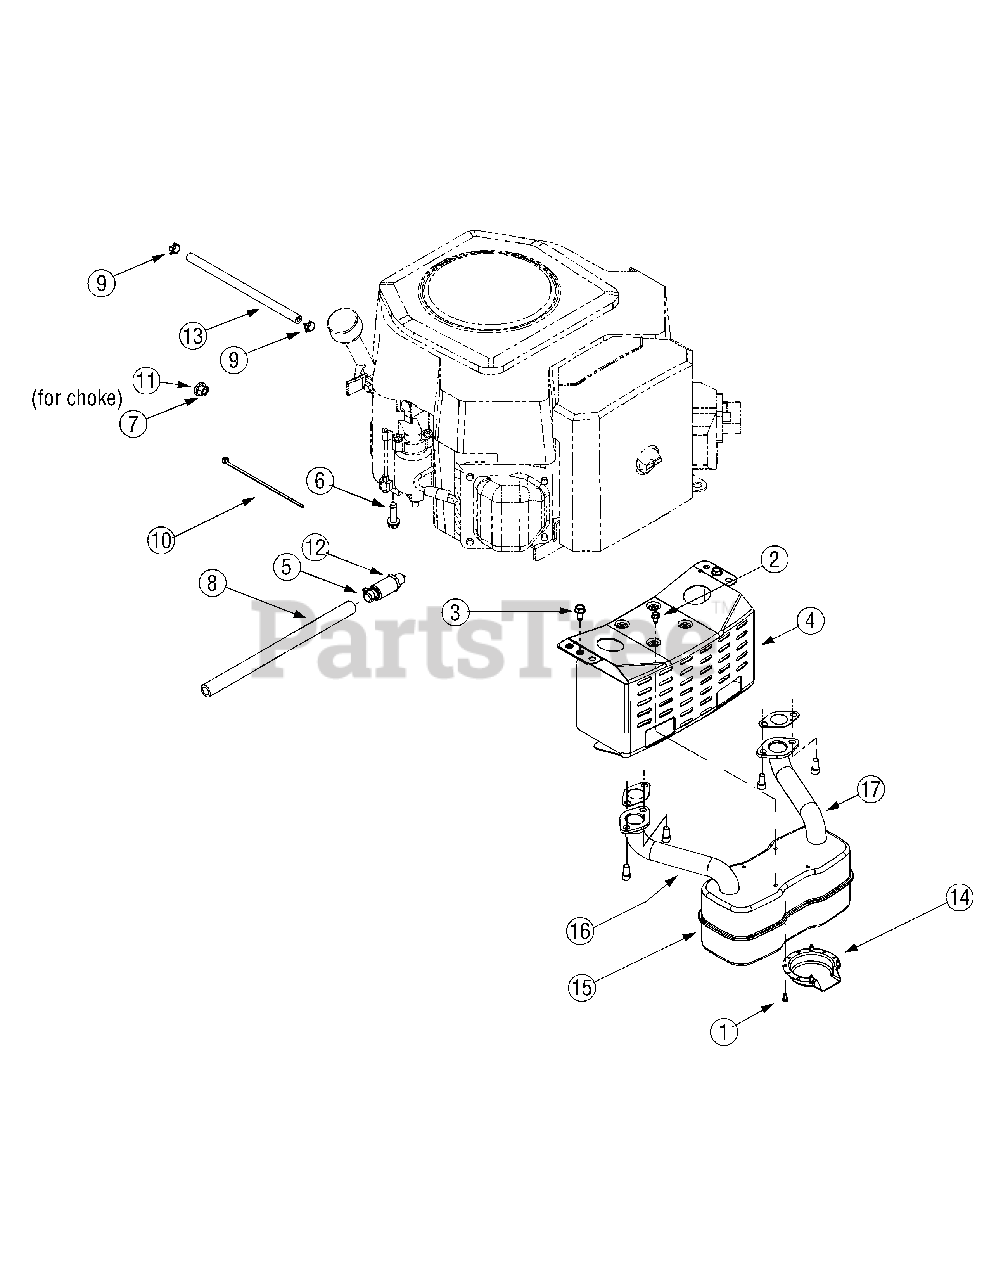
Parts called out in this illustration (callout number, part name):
1	Screw, #8-18 x.50
2	Screw, 1/4-20 x.50
3	Screw, 5/16-18 x.750
5	Oil Drain Cap
6	Self-tapping Screw, 3/8-16 x 1.00
7	Flange Lock Nut, 3/8-16
8	Oil Drain Hose
11	Lock Washer,.406 x.875 x.059
12	Oil Drain Valve
13	Fuel Line Hose
14	Muffler Deflector
15	Muffler, Twin Inlet
16	RH Exhaust Pipe
17	LH Exhaust Pipe
